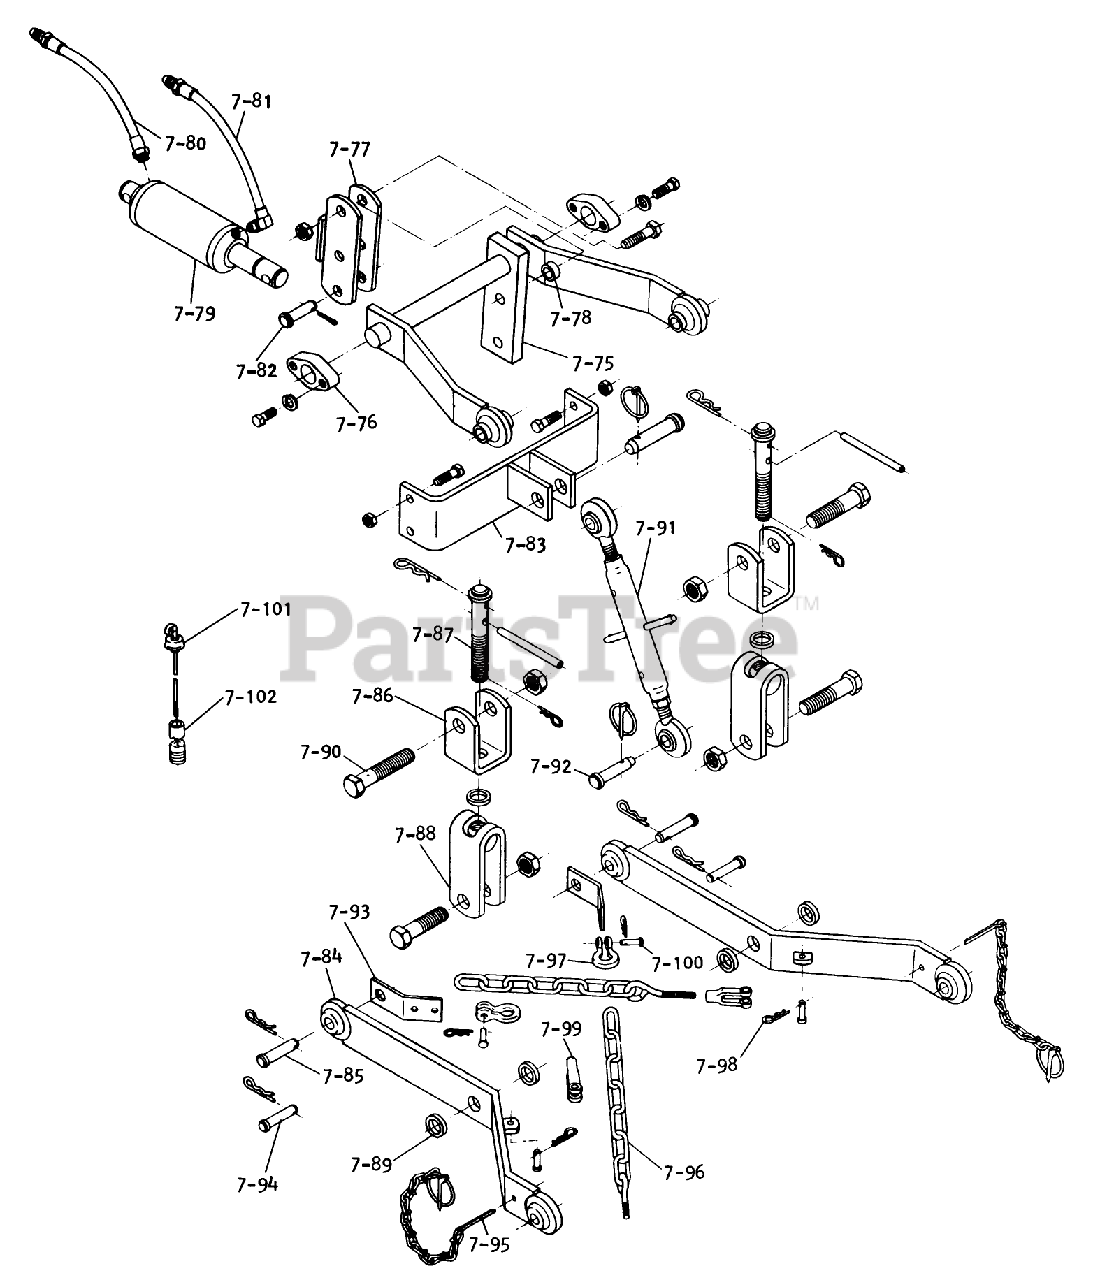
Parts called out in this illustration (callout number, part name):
7-89	SPACER
7-92	PIN HITCH UPPER LINK
7-97	ORDER 105820 & 105821
7-99	CLEVIS
